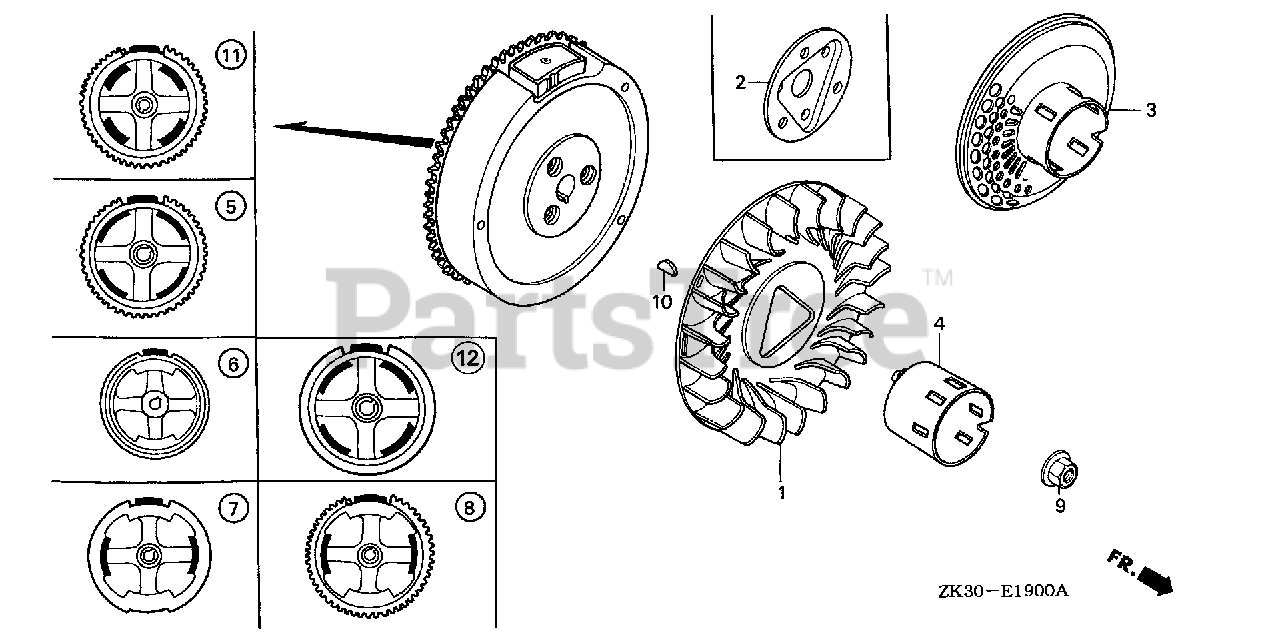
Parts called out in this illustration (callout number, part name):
1	FAN, COOLING
3	PULLEY, STARTER (SCREEN GRID)
4	PULLEY, STARTER
8	FLYWHEEL (SEL-LAMP)
9	NUT, SPECIAL (16MM)
10	KEY, SPECIAL WOODRUFF (25X18)
